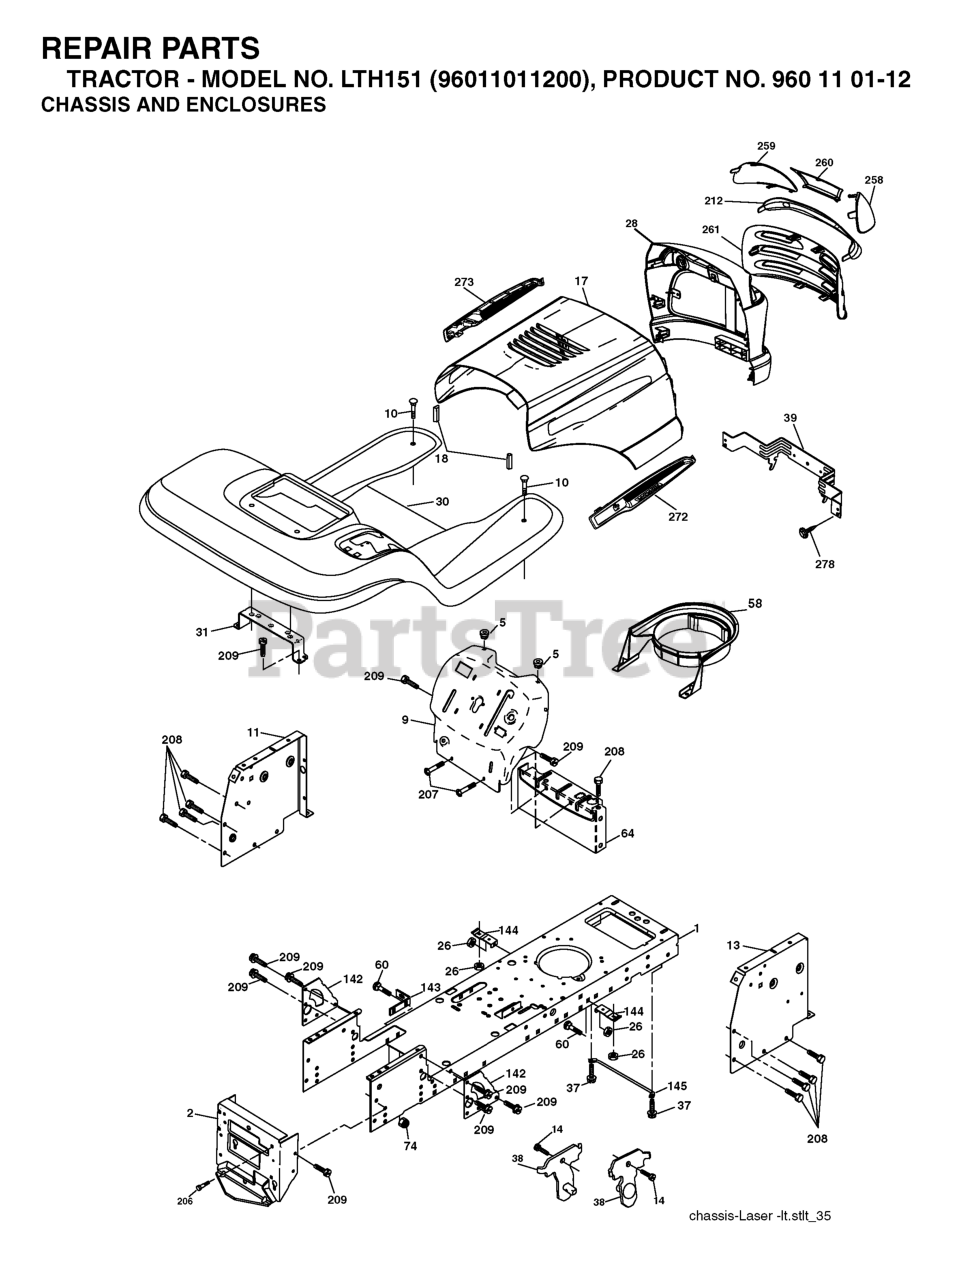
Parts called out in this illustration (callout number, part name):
1	CHASSIS STAMPING
2	DRAWBAR, 12GA
5	BUMPER.RUBBER.HOOD
9	FENDER.STL.W/O CUPHLDR.ROS.422
10	BOLT D
11	PANEL.DASH.LH.LTX
13	PANEL DASH RH
17	VENT.HOOD.LASER.III
18	BUMPER.HOOD.LARGE.1.75"
26	NUT
31	BRACKET.SUPPORT.FENDER
37	Screw 5/16-18 x 1/2 Hex, Self Tapping 5/16-18 x 1/2
38	BRACKET.ASM.PIVOT.MOWER.REAR
39	BRACKET PIVOT LASER
60	Bolt - Rd. Hd. Sq. Neckiage 3/8 16 x 3/4
64	DASH LOWER
142	PLATE REINFORCEMENT
143	BRACKET, SWAYBAR CHASSIS
144	BRKT, FOOT REST
145	ROD PIVOT CHASSIS/HOOD
206	SHOULDER BOLT 5/16-18TT
207	SCREW, 5/16-18 X 1/2
208	SCREW 3/8-16X1/2
209	SCREW, 3/8-16X3/4
212	INSERT.LENS.REFLECTIVE
258	LENS LH
259	LENS LH
260	COVER.LENS.HUSQ.LASER
272	VENT.HOOD.LASER.
273	VENT.HOOD.LASER.
278	SCREW
